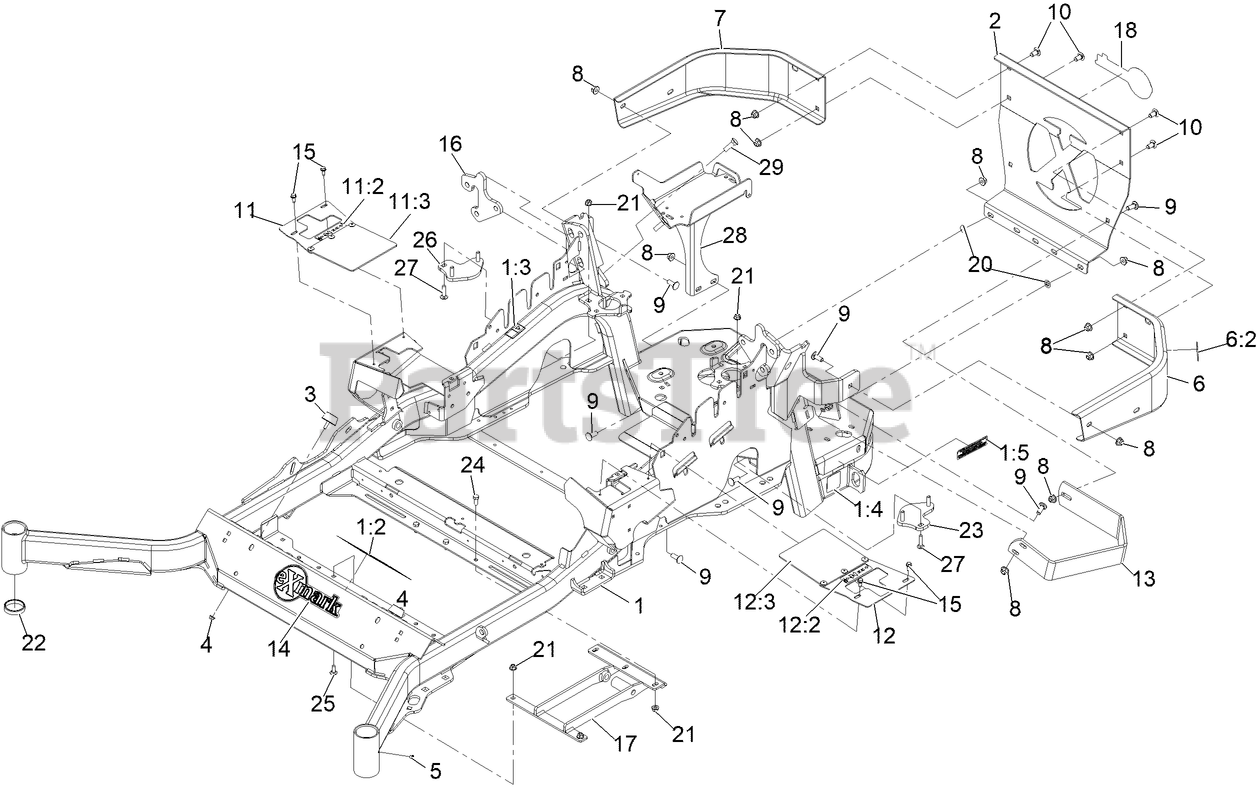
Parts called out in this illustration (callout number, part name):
1	MAINFRAME SERVICE ASM - 72
1:2	DECAL-WARNING
1:3	DECAL-DANGER
1:4	DECAL-HAZARD, PINCHED FINGER
1:5	DECAL-ARRESTOR, SPARK
2	PLATE,REAR GUARD
6	LH BUMPER ASM
6:2	DECAL-WARNING
7	BUMPER-RH
8	NUT-HF, NI
9	SCREW-CARR
10	SCREW-CARR
11	RH MOTION CONTROL COVER A
11:2	DECAL-CONTROL, MOTION
11:3	FLAP-RUBBER
12	LH MOTION CONTROL COVER A
12:2	DECAL-CONTROL, MOTION
12:3	FLAP-RUBBER
13	GUARD-MUFFLER
14	DECAL-EXMARK
15	SCREW-HWH
16	PLATE-MOUNT, SHOCK
17	MOUNT-LOWER
18	DECAL, EXMARK LOGO
20	NUT-PUSH
21	NUT-HF, NI
22	CUP-BEARING
23	LH PLATE ASM (W/STUDS)
24	SCREW-HH
25	SCREW-CARR
26	RH PLATE ASM (W/STUDS)
27	Bolt-Carriage 5/16-18 X 1 1/4
28	BATTERY MOUNT ASM
29	BOLT-CARR
